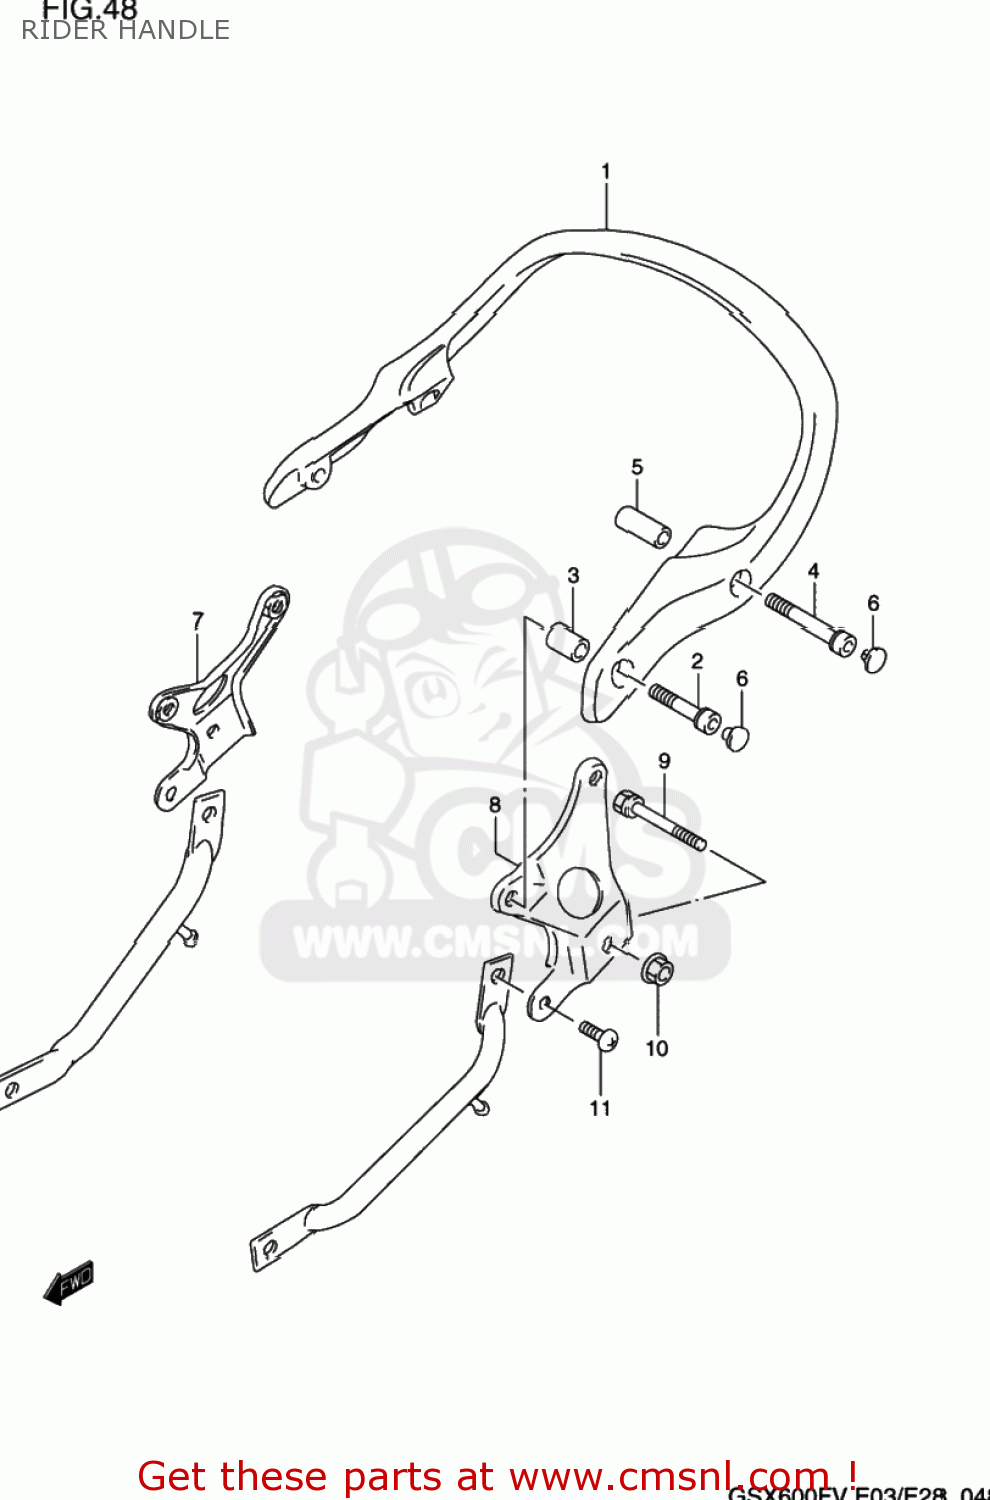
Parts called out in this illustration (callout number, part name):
1	HANDLE,PILLION RIDER
2	BOLT
3	SPACER(8.5X14X21.5)
4	BOLT
5	SPACER(8.5X14X28)
6	CAP(OD:14.5)
7	BRACKET,PILLION RIDER HANDLE,R
8	BRACKET,PILLION RIDER HANDLE,L
9	BOLT
10	NUT
11	SCREW
